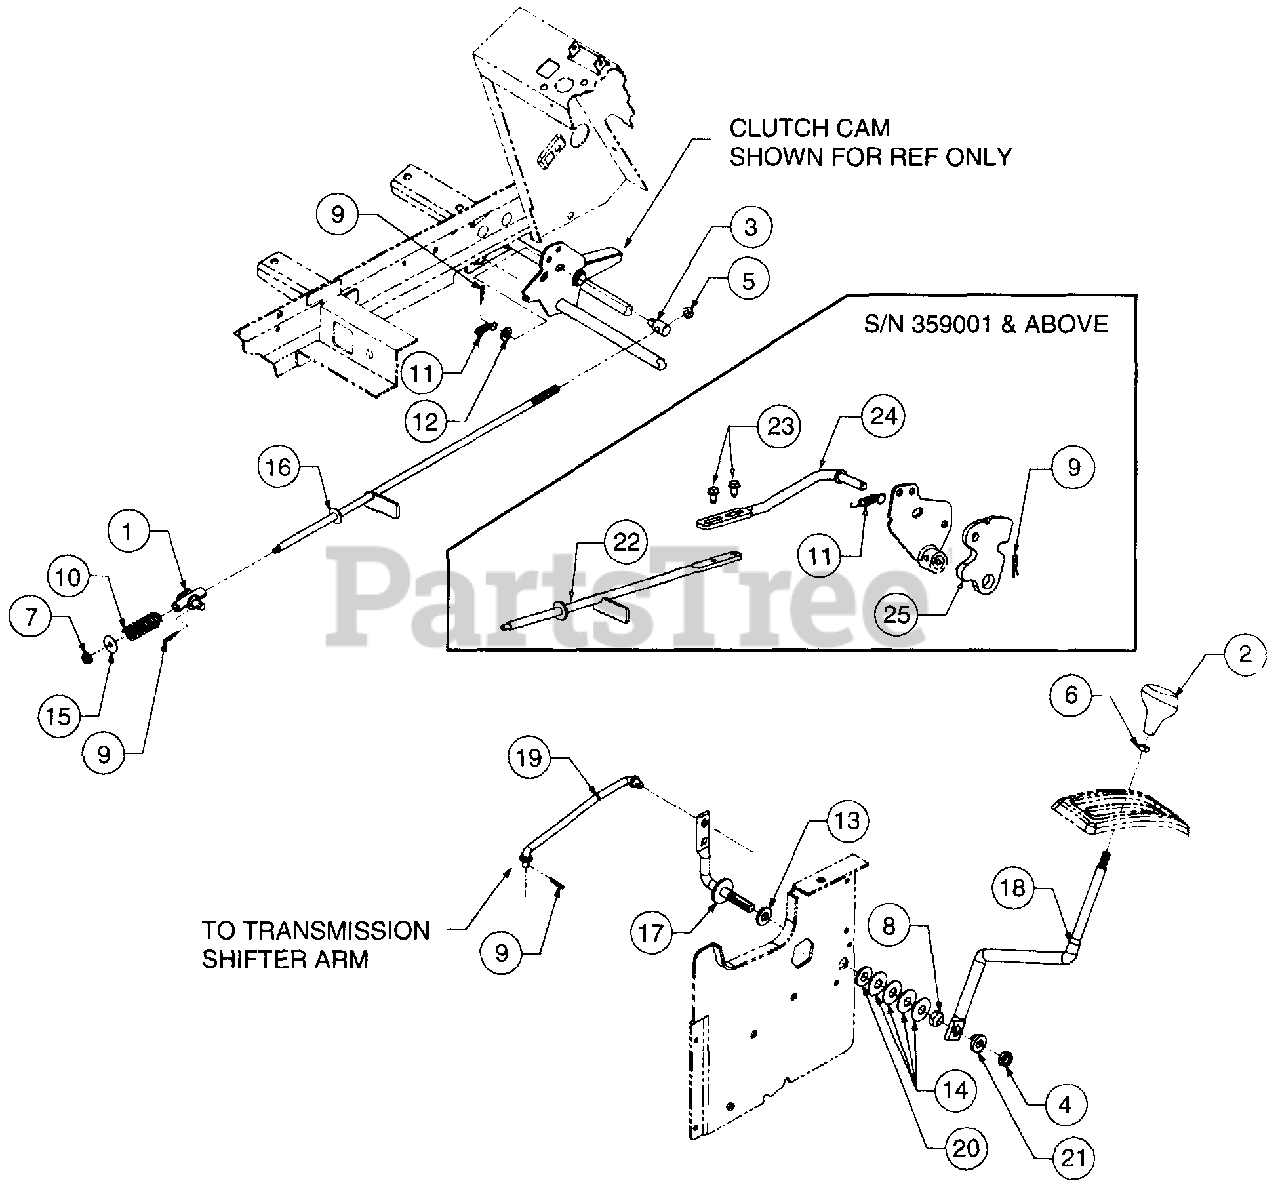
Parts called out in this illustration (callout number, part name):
1	Pivot Assy, Sleeve
2	Knob, Shifter
3	Ferrule, Adjustment
4	Nut, Hex Top Lock, 1/2-20
5	Nut, Hex Jam, 3/8-24 GR5
6	Nut, Hex Jam, 3/8-16 GR5
7	Nut, Hex Flange Lock, 1/4-20
8	Nut, Hex, 1/2-20
9	Pin, Internal Cotter, 5/16 x 1.12
10	Spring, Compression, .63 ID x 2.0 Lg
11	Spring, Extension, .38 OD x 1.44 Lg
12	Washer, Flat, .406 x .75 x .063
13	Washer, Flat, .510 x 1.0 x .125
14	Washer, Bell, .406 x .75 x .063
15	Washer, Flat, .265 x 1.0 x.030 Hdn
16	Rod, Clutch Adjustment
17	Rod, Shift
18	Rod, Gear Selector
19	Link, 6-Speed Shifter
20	Bushing, Shoulder
21	Hub, Shift
22	Rod, Clutch
23	Screw, Hex Wash Hd Tapp, 1/4-20 x .5
24	Rod, Front Control
25	Plate, 6-Speed Cruise
